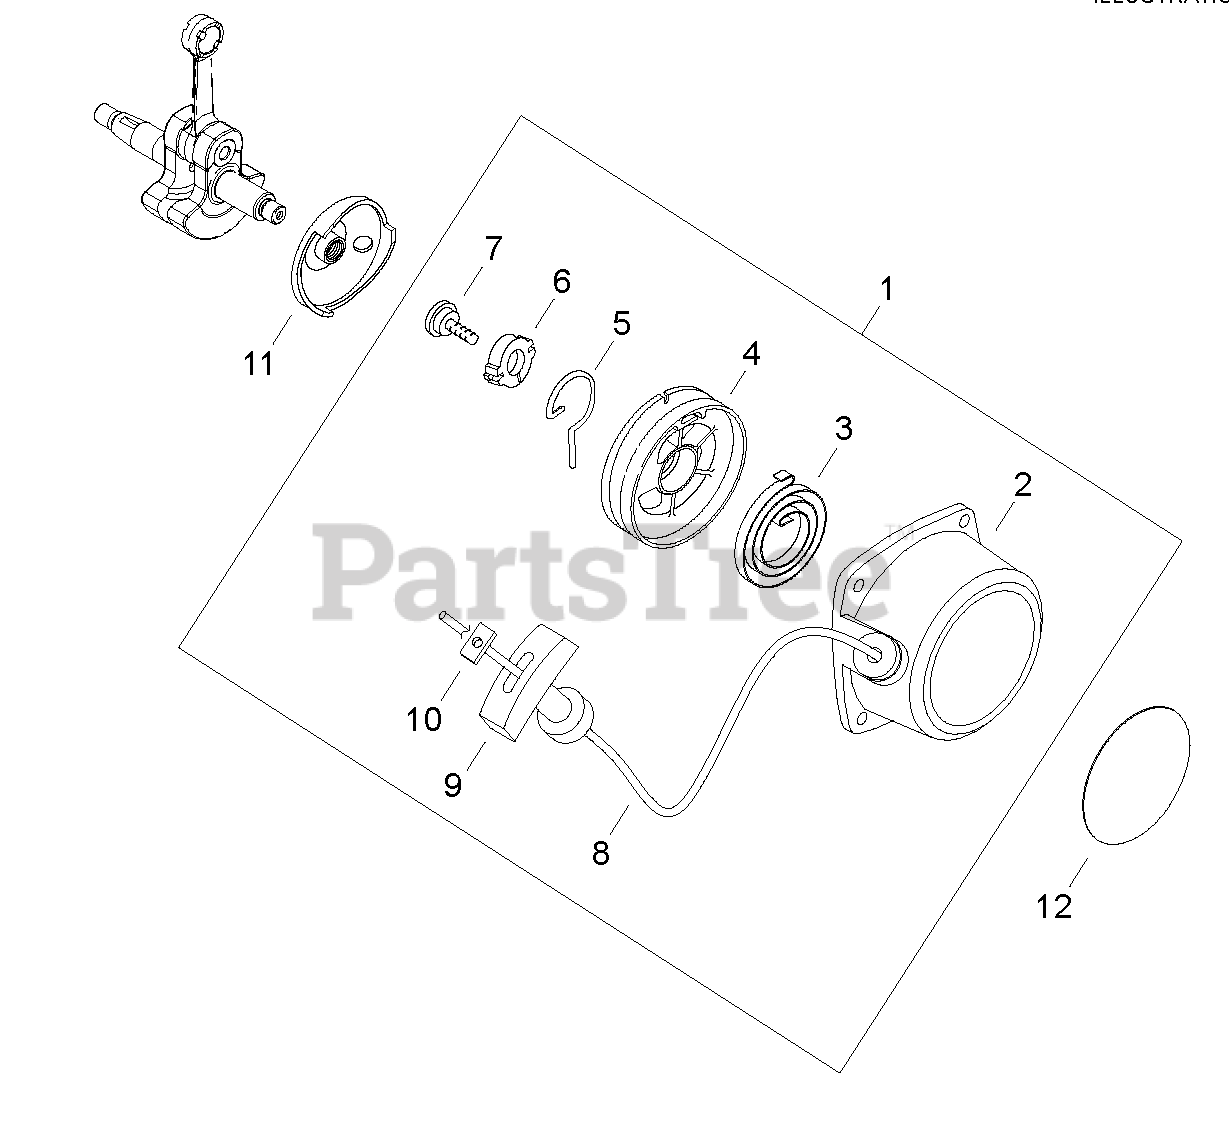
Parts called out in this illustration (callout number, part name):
1	STARTER ASSY
2	CASE, STARTER
3	SPRING, REWIND
4	REEL, ROPE
5	CATCHER, PAWL
6	WASHER - 5
7	SCREW - 5
8	ROPE, STARTER
9	GRIP, STARTER
10	RETAINER, ROPE
11	STARTER PAWL ASSY
12	LABEL - MODEL C282
